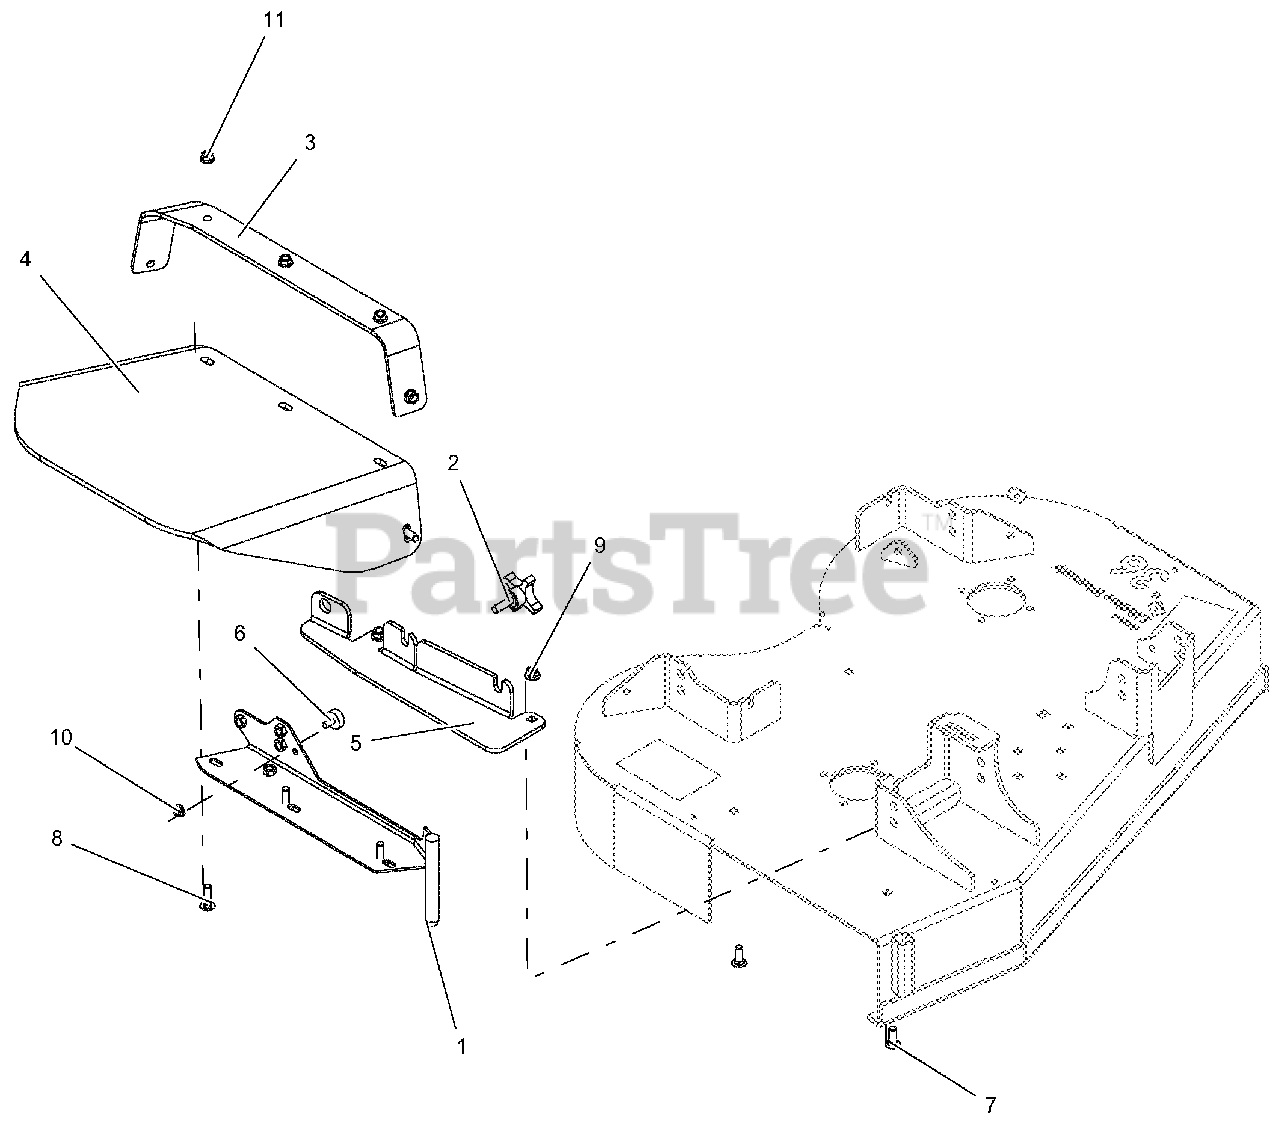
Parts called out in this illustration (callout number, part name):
1	W LDT. DISCHARGE-RED
2	KNOB, 3/8 X 1.25 - 4 PRONG
3	STRAP, RUBBER DISCHARGE CHUTE
4	SHIELD, RUBBER DISCHARGE
5	BRKT, DISCHARGE 36 STANCE
6	BUMPER, RUBBER
7	BLT-RDHDSQNK .38-16X1.00 G5 YWZC
8	BLT-RDHDSQNK .38-16X1.25 G5 YWZC
9	NUT-LK-NYL-FLG .38-16 YWZC
10	@ NUT-SPNLK-FLG .312-18 YWZC
11	@ NUT-SPNLK-FLG .375-16 YWZC
